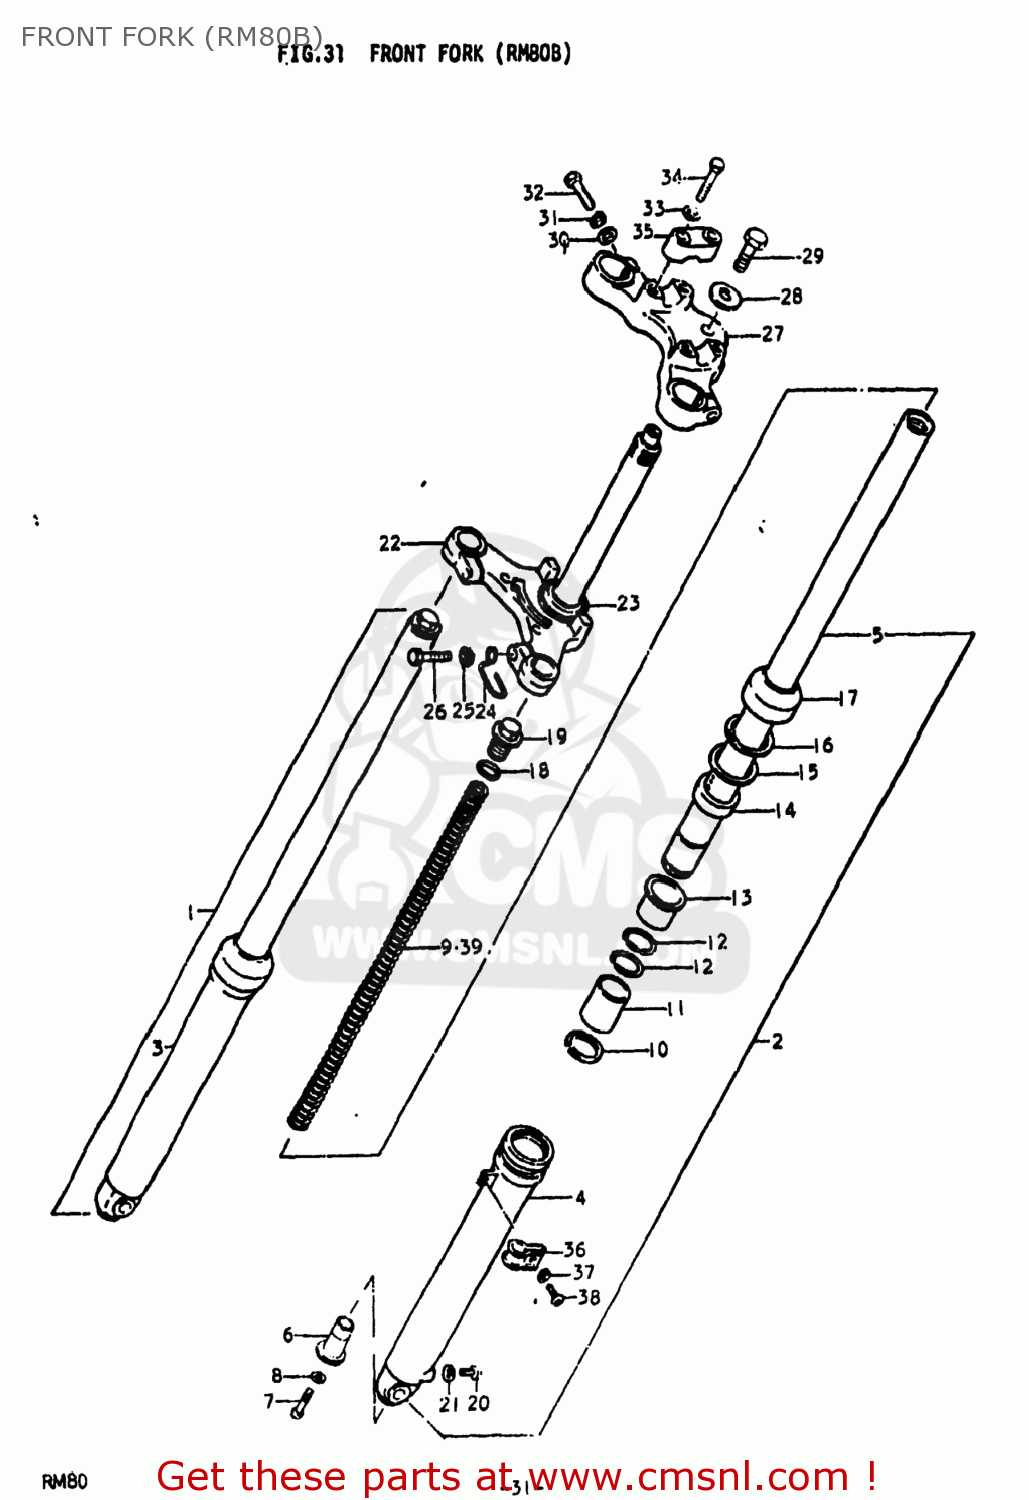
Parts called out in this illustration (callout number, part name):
1	DAMPER ASSEMBLY,RIGHT
2	DAMPER ASSEMBLY,LEFT
3	TUBE,OUTER,RIGHT
4	TUBE,FORK,LEFT,OUTER
5	TUBE,FORK,INNER
7	SCREW
8	GASKET (NAS)
9	SPRING
13	BUSHING,GUIDE
14	OIL SEAL,FRONT FORK
15	WASHER
16	CIRCLIP
17	BOOT
18	O-RING,FORK INNER TUBE
19	CAP,FORK
20	SCREW
21	GASKET (NAS)
22	STEM,STEERING
23	RACE,STEERING OUTER LWR
24	CLAMP,METER CABLE
25	LOCK WASHER
26	BOLT 10X30
27	HEAD,STEERING STEM
28	WASHER(10.5X30X2.3)
29	BOLT
30	WASHER
31	LOCK WASHER
32	BOLT
33	LOCK WASHER
34	BOLT
35	HOLDER,HANDLEBAR
36	CLIP,CABLE
37	LOCK WASHER
38	SCREW
39	SPRING
